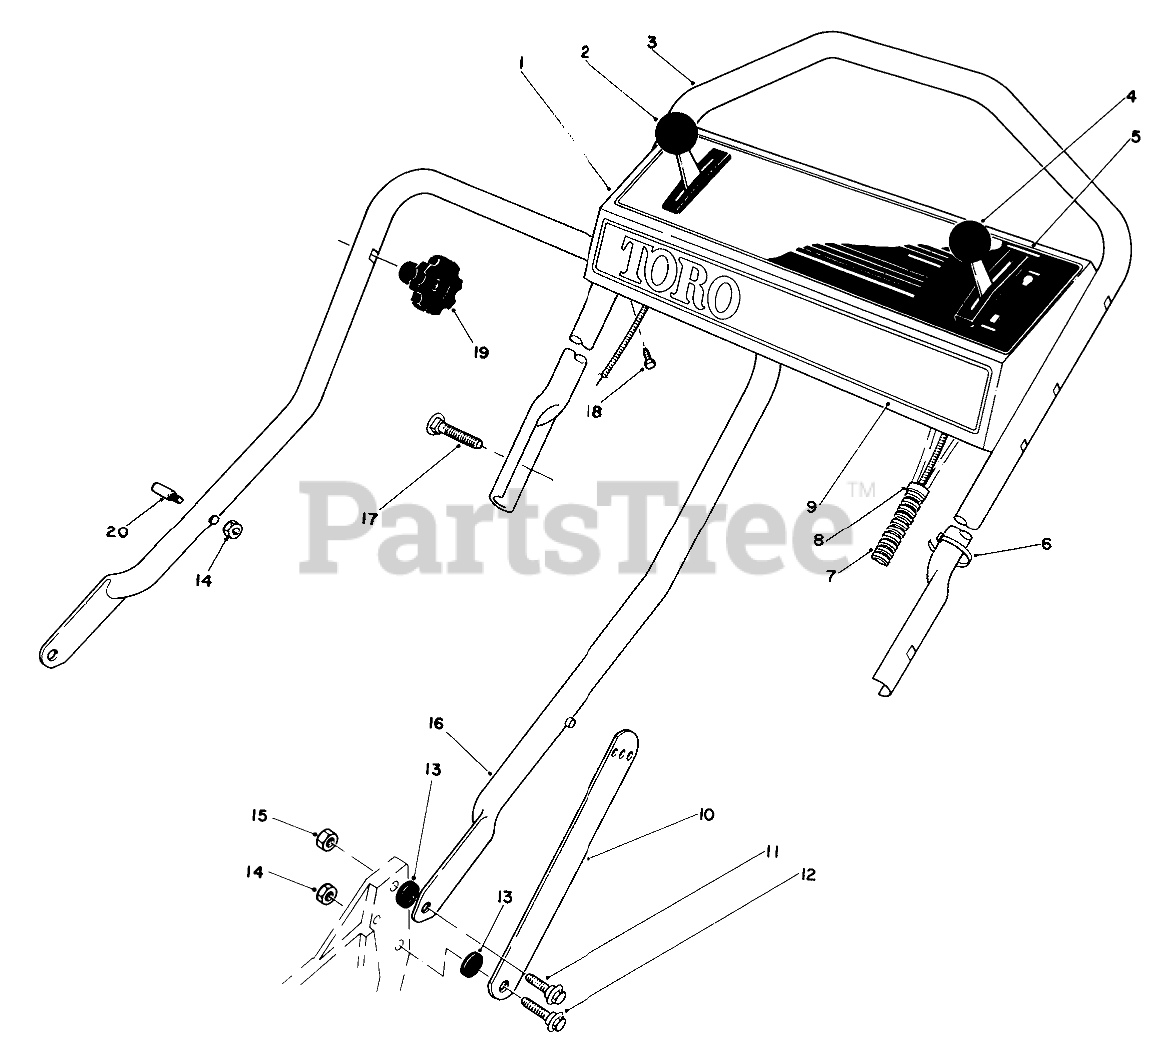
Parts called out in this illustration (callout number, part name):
1	Panel-Control (Incl. Ref. #5)
2	GROUND SPEED CONTROL
3	Handle-Upper
4	SERVICE THROTTLE CONTRO
5	Decal-Instruction Panel
6	TIE-CABLE
7	CONTROL CABLE COVER
8	Clip-Convoluted Tubing
9	Decal-Toro
10	Handle Latch
11	SCREW-SHOULDER
12	SCREW-SHOULDER
13	SPACER
14	NUT-LOCK, NI
15	NUT-LOCK, NI
16	Handle-Lower
17	5/16-18 X 2 HNDLE SCREW
18	SCREW-HWHTF
20	HANDLE PIN
